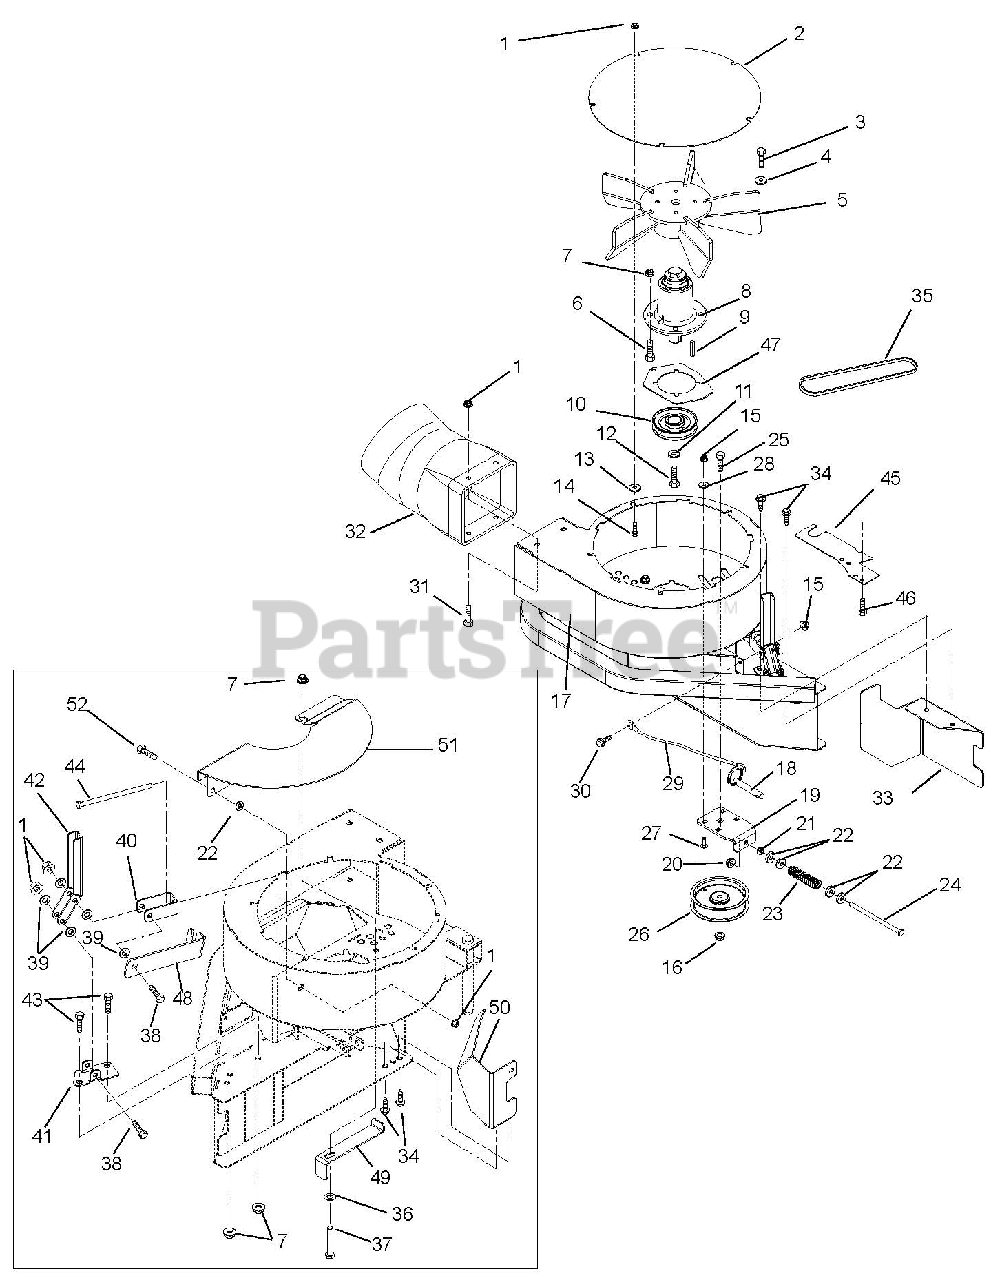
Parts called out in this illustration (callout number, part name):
1	Nut, .31-18 Nyloc Flange
2	Cover, Blower
3	Bolt, Hex .62-18 x 1.75
4	Washer, Bevelled .63 x 1.625 x .14
5	Weldment, Impeller
6	Bolt, Hex .38-16 x 1.25 Grade 5
7	Nut, .38-16 Nyloc Flange
8	Maintenance Free Spindle Assembly
9	Key, Square .25 x .25 x 1.00 RC 40-50
10	Weldment, Pulley-V 3.50 x 1.004 with Key
11	Washer, Flat Steel .39 x 1.5 x .125
12	Bolt, Hex .38-16 x 1.00 EP30
13	Nut, Push .312
14	Bolt, Round Head Square Short Neck .31-18 x .75 Grade 5
15	Nut, Locking-Top-Flange .25-20
16	Nut, .38-16 Nyloc Flange
17	Weldment, Blower Housing
18	Pin, Spring Ball .375OD x 1.50
19	Bracket, Adjustable Idler
20	Nut, .31-18 Nyloc Flange
21	Nut, Spin Lock-Flange .312-18
22	Washer, Flat Steel .38 x .87 x .179
23	Spring, Compression .092 x .77 x 3.13
24	Bolt, Hex .31-18 x 5.50 Grade 5
25	Bolt, Hex .38-16 x 1.75 Grade 5
26	Pulley, Idler 4.00
27	Bolt, Round Head Square Neck .25-20 x .75 Grade 5
28	Bushing, Flange .265 x .437 x .250 x .750
29	Cable, Hood
30	Bolt, Hex .25-20 x .75 Grade 5
31	Bolt, Hex .31-18 x .75 Grade 5
32	Adapter, Hose
33	Baffle, Blower 52"
33	Baffle, Blower 60"
34	Screw, Tapping .38-16 x .50 Hex Washer Head
35	V-Belt, 52" Mower Deck
35	V-Belt, 60" Mower Deck
35	V-belt, 66" Mower Deck
36	Washer, Flat, STL .406 x .812 x .065
37	Bolt, Hex .38-16 x 1.00 Grade 5
38	Bolt, Hex .31-18 x 2.00 Grade 5
39	Washer, Flat - Nylon .375 x .75 x .060
40	Link, Idler Release
41	Mount, Idler Release Lever
42	Lever, Idler Release
43	Bolt, Hex .38-16 x .75 Grade 5
44	Bolt, Hex .31-18 x 5.50 Grade 5
45	Finger Guard
46	Bolt, Hex .25-20 x .50 Grade 5
47	Plate, Bearing Housing Support
48	Lock, Idler Release Lever
49	Finger - Belt
50	Baffle, Blower - Rear - 52"/60"/66"
51	Cover, Bottom Plate
52	Bolt, Hex .31-18 x 0.75
